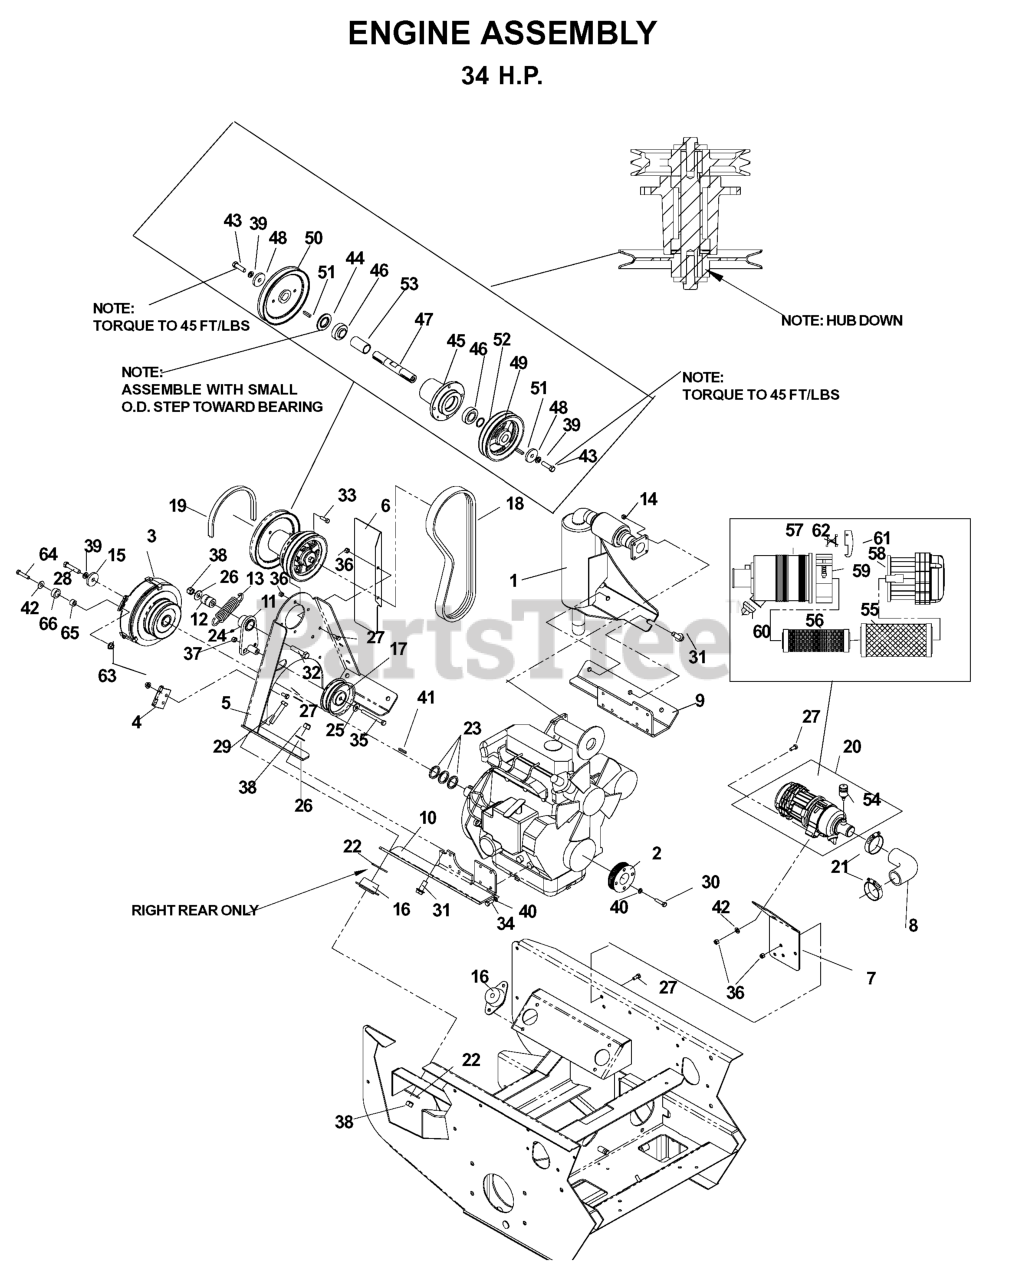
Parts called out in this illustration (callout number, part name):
1	MUFFLER TURBO
2	ENGINE SHEAVE
3	ELECTRIC CLUTCH
4	RESTRAINT KIT
5	JACKSHAFT MOUNT WELDMENT
6	HEAT SHIELD
7	MOUNTING BRACKET
8	AIR FILTER HOSE
9	ENGINE MOUNT-LT
10	ENGINE MOUNT-RT
11	ARM WELDMENT
14	NUT M8-1.25 STOVER
15	SPINDLE WASHER
18	BELT, PRIMARY BZ
19	ENGINE, BELT MULE
20	AIR FILTER ASSY
21	CLAMP, AIR HOSE
22	WASHER, HEAVY
23	BUSH 1-1/8 X 10 GA ZD
24	GREASE ZERK LONG
25	WASHER 3/8 SAE FLAT
26	WASHER 1/2 FLAT
27	HCS 5/16C X 3/4
28	BOLT 7/16F X 2 1/2
29	HCS 1/2C X 2 3/4
30	HTB M8-1.125 X 25MM
31	HCS 1/2C X 1 1/4 SERRATED HEAD
32	HEX SCREW 1/2-13 X 2.5" GR 5
33	HCS 5/16C X 1
35	HCS 3/8-16 X 3-1/2 GR5 ZD
36	NUT 5/16 NYLOC
37	NUT 3/8-16 NYLOC
38	NUT 1/2-13 HEX NYLOC ZD
39	WASHER 7/16 LOCK
40	WASHER.LOCK.HVY.HLCL.SPR.5/16
41	KEY 1/4 SQ X 2-1/2
42	WASHER 5/16 FLAT
43	HCS 7/16F X 1 1/2
44	COMBO SPACER
45	HOUSING, DIE CAST
46	BEARING
48	SPINDLE WASHER
51	KEY 1/4 SQ X 1 1/8
52	BUSHING.MACHINE.18.GAUGE
55	AIR FILTER
56	SAFETY ELEMENT
57	BODY, STRAIGHT
58	PRECLEANER ASM
59	MOUNTING BRACKET
63	NUT 5/16C WHIZ
64	HCS 5/16C X 1 1/4
